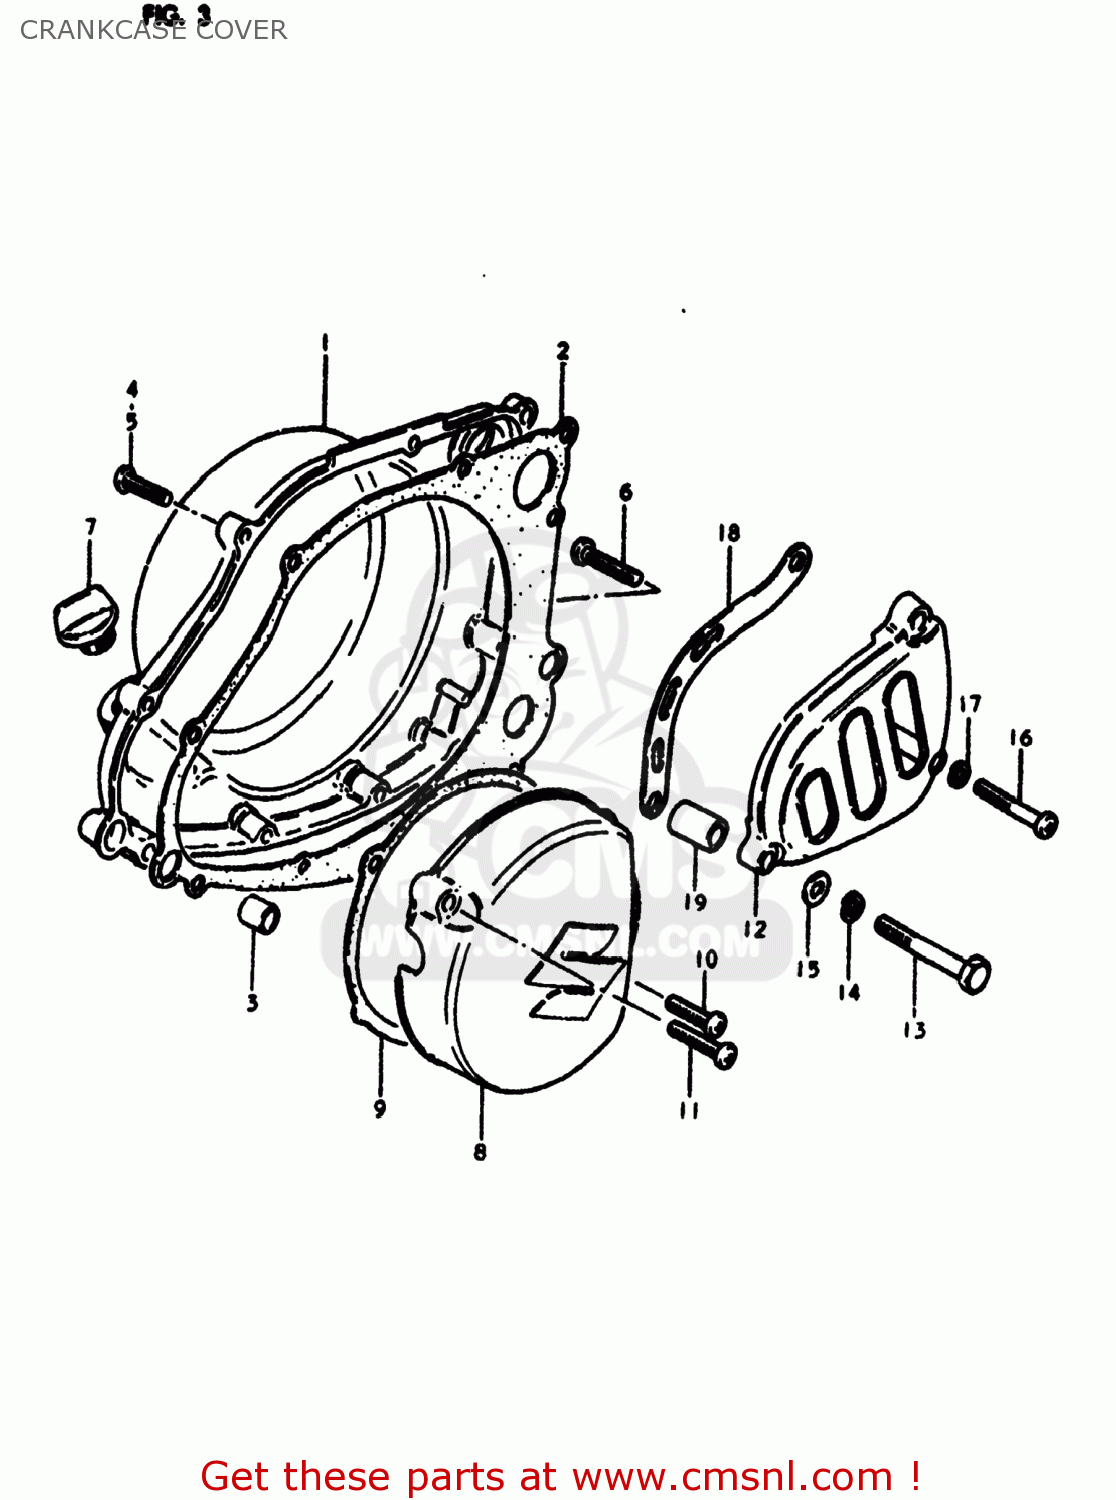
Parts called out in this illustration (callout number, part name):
1	COVER,CLUTCH
2	GASKET,CLUTCH COVER (MCA)
3	PIN
4	SCREW
5	SCREW 6X30
6	SCREW (6X45)
7	PLUG,OIL FILTER
8	COVER
9	GASKET,MAGNETO COVER (MCA)
10	SCREW
11	SCREW 6X30
12	COVER,ENGINE SPROCKET
13	BOLT 8X55
14	LOCK WASHER
15	WASHER
16	SCREW
17	LOCK WASHER
18	PLATE,FR CHAIN GUIDE
19	SPACER(8.6X16X24)
